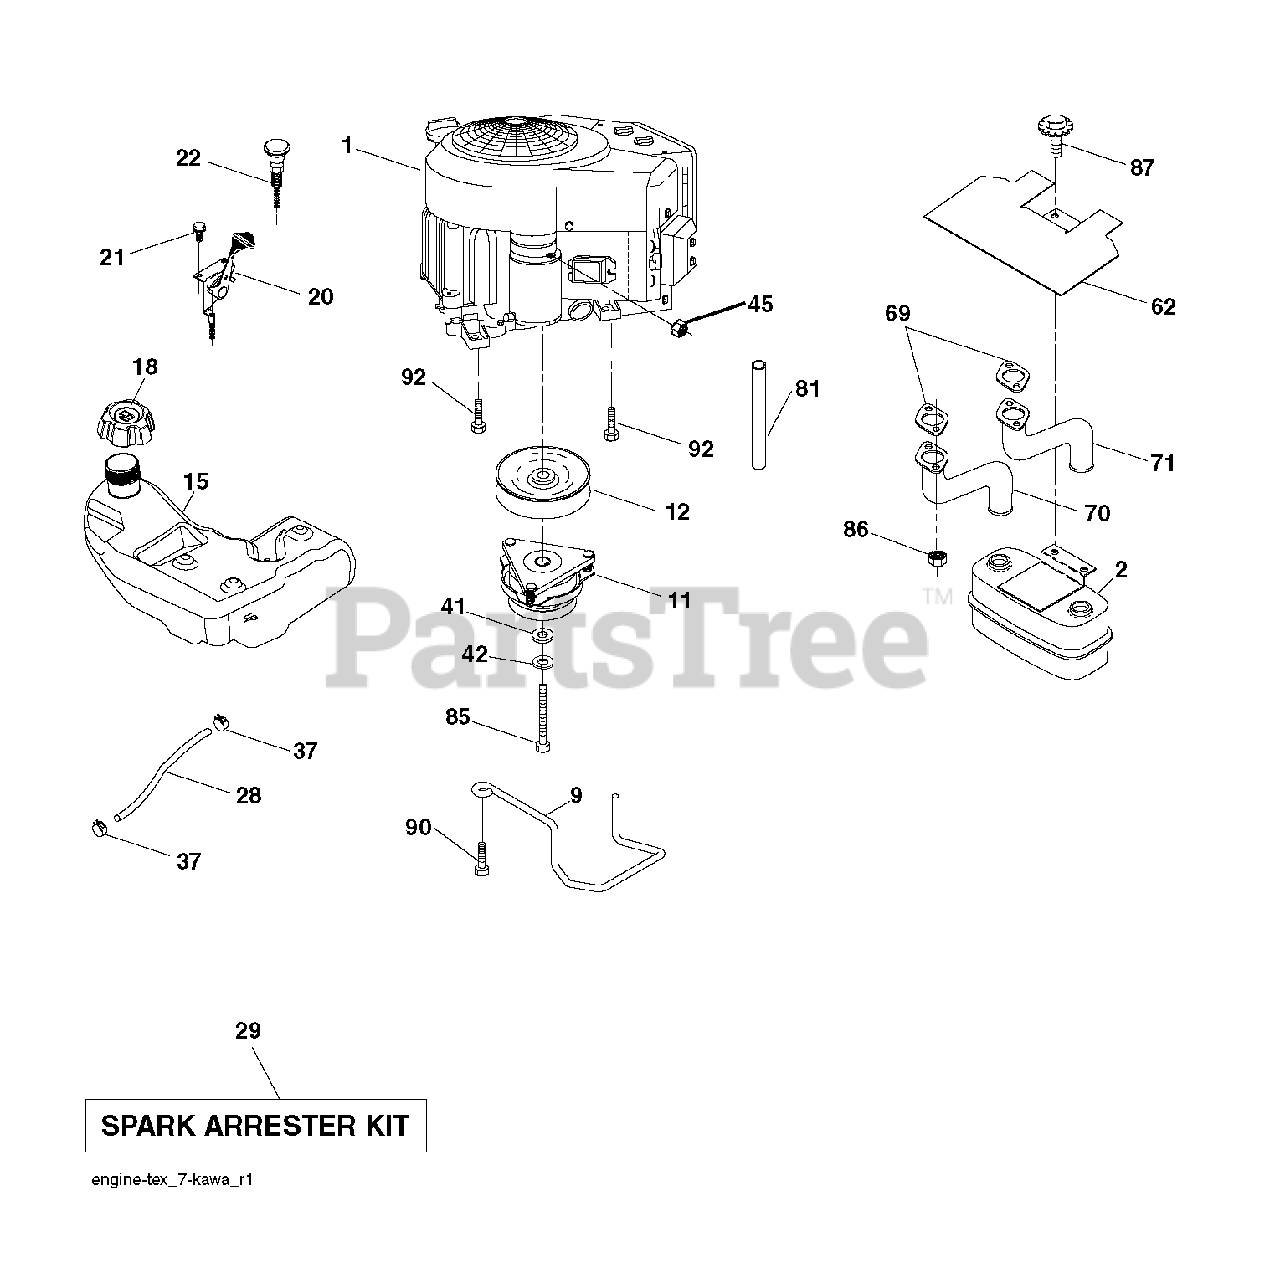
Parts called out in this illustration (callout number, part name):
2	MUFFLER.ASM.TWN.EXTNDED.DFLCTR
9	KEEPER.BELT.ENGINE.4.2
11	RB.CLUTCH.OGURA.4.4.PD
12	PULLEY.ENGINE.TUFFTORQ
15	TANK.FUEL.4GAL
18	CAP.FL.R.3'N/CARB.H.CROWN.498
20	CONTROL.THROTTLE.COBRA.BLACK
21	SCREW.#10 X 0.750.BOS
22	CONTROL.CHOKE.ERGO.PUSH-IN.BLA
28	REPL BY 532 00 85-43
29	KIT.SPARK ARRESTOR 794945 B&S
37	HOSE CLAMP
42	LOCKWASHER
45	NUT
62	SHIELD.HEAT.MUFFLER
70	TUBE.EXHAUST.LH.FR961/FR730
71	TUBE.EXHAUST.RH.FR961/FR730
81	TUBE, DRAIN OIL ASM.
85	BOLT HEX 7/16-20X4-1/4"
86	NUT.HEX.FLANGE.TOPLOCK
87	BOLT, 5/16-18 X 1 3/4
90	SCREW 3/8-16X1
92	SCREW 3/8-16X1
